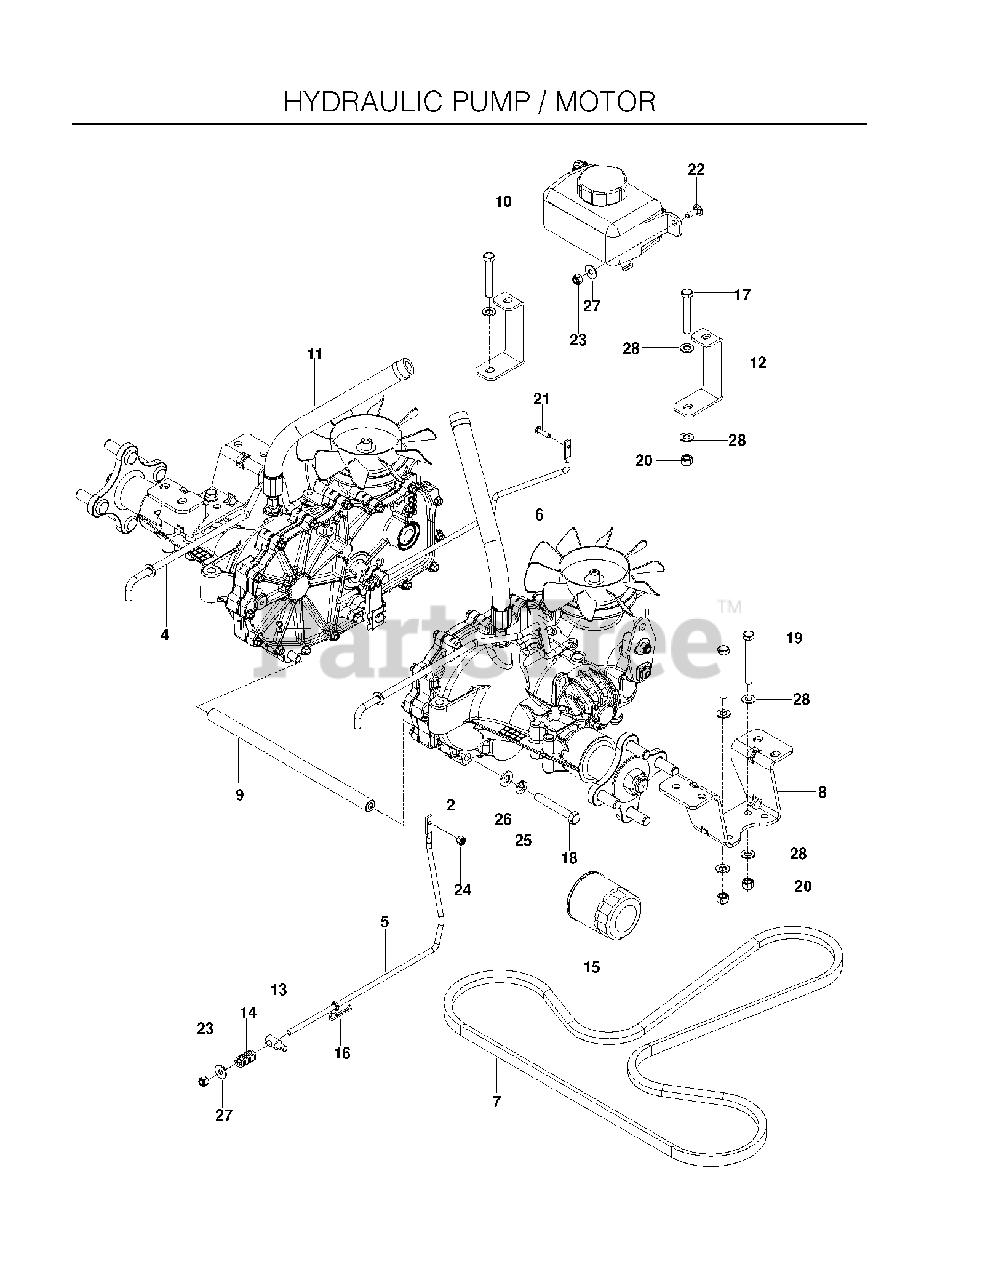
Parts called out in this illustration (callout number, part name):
1	TRANS, ZT-2800 RT
2	TRANS, ZT-2800 LEFT
3	ROD, BYPASS, RT
4	ROD, BYPASS, LT
5	LINKAGE, BRAKE RT
6	LINKAGE, BRAKE, LT
7	EZT HYDRO BELT
8	EZT MOUNT, REAR, BLACK
9	SPACER TUDE, EZT, 11.08
10	EXPANSION TANK W/CAP
11	HOSE ASSY
12	SUPPORT FRT TRANS, BLK
13	BRAKE SWIVEL
15	FILTER, ZT4800
16	HAIRPIN #2
17	CAPSCREW
18	HCS 3/8C X 2 1/2
19	HCS 5/16C X 2-3/4
20	NUT 5/16 NYLOC
22	RHSNB 1/4C X 3/4
23	NUT 1/4-20 NYLOC
24	NUT 10-24 NYLOC
25	SLW 3/8 STD
26	WASHER 3/8 SAE FLAT
27	WASHER 1/4 FLAT
28	FLAT WASHER 5/16 SAE
